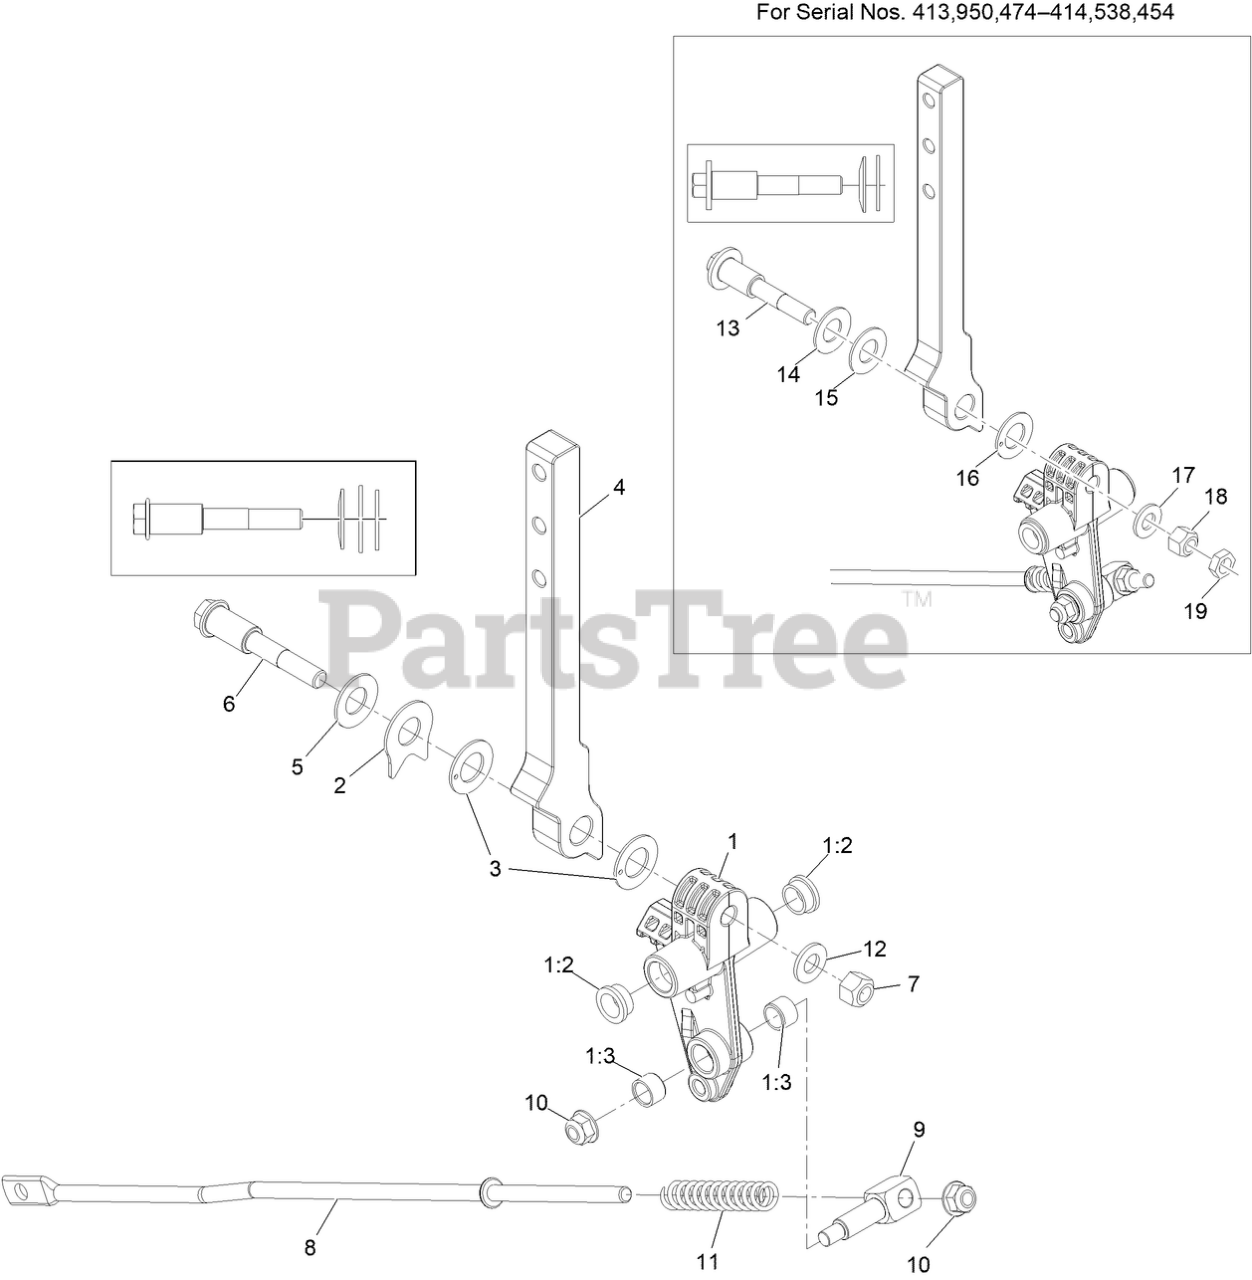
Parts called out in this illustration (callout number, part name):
1	CONTROL ARM ASM
1:2	BUSHING
1:3	BUSHING-SLEEVE
2	Spacer, Anti-Rotation
3	WASHER-FRICTION
4	Lever, Motion Control
5	WASHER-BELLEVILLE
6	Bolt-Pivot
7	NUT-LOCK, CONE
8	LINK-CONTROL
10	NUT-HF, NI
11	SPRING-RETURN, NEUTRAL
12	WASHER-FLAT
13	BOLT-PIVOT
14	WASHER-BELLEVILLE
16	WASHER-FRICTION
17	WASHER-FLAT
18	NUT-LOCK, CONE
19	NUT-JAM
